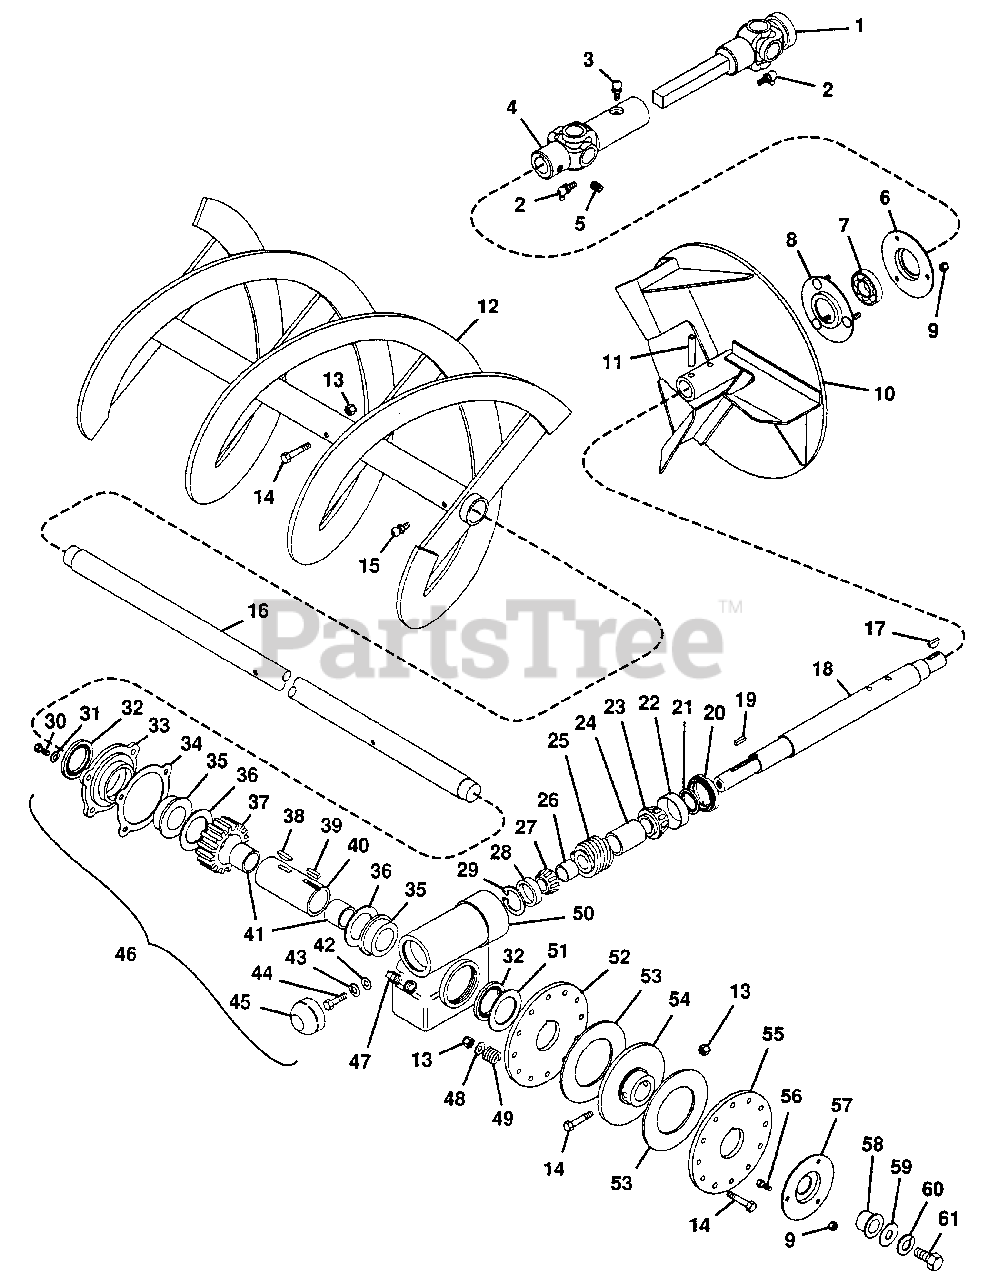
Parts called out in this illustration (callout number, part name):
1	Shaft, Prop. Sq. Bar
2	Fitting, Lube 90 Degree
3	Fitting, Lube 1/4-28
4	U-Joint, Female
5	Screw, Set 3/8-16x.375
6	Bearing, Flange
7	Bearing, Ball
8	Bearing, Flange
9	Nut, Lock 1/4-20
10	Fan, 16"
11	Pin, Roll 5/16x1.75
12	Rake, Right 40"
12	Rake, Right 48"
12	Rake, Left 40"
12	Rake, Left 48"
13	Nut, Lock 5/16-18
14	Bolt, Hex 5/16-18x2.00
15	Fitting, Lube 1/4-28
16	Shaft, 40" Rake
16	Shaft, 48" Rake
17	Key, Woodruff .187x.875
18	Shaft, Worm 16"
19	Key, Straight SAE 1035
20	Plug, Adjustment
21	Seal
22	Cup, Bearing
23	Cone, Bearing
24	Spacer, Bearing
25	Worm
26	Spacer, Bearing
27	Cone, Bearing
28	Cup, Bearing
29	Ring, Snap Internal 1.781
30	Bolt, Hex 1/4-20x.875
31	Washer, Lock 1/4 Ext Th TYA
32	Seal
33	Cover, Gearcase
34	Gasket
35	Bushing, Flange 1.62x1.87x11
36	Washer, 1.625x2.50x.012
37	Gear, Worm
38	Key, Feather
39	Key, Straight
40	Shaft, Gearcase
41	Bushing, Sleeve
42	Washer, Flat .344x.688x.065
43	Washer, Lock 5/16 SP
44	Bolt, Hex 5/16-18x.75
45	Cap, Dust
46	Assembly, Gearcase
47	Plug, Pipe
48	Washer, Flat .312x.734x.065
49	Spring, Compression
50	Gearcase
51	Washer
52	Driver
53	Disc, Friction
54	Plate, Driver
55	Plate, Pressure
56	Bolt, Rib Neck 1/4-20x.5
57	Support, Bearing
58	Bushing, Flange 1x1.12x.625
59	Washer, Flat .515x1.441x.1
60	Washer, Lock 1/2 SP Heavy
61	Bolt, Hex 1/2-13x1
